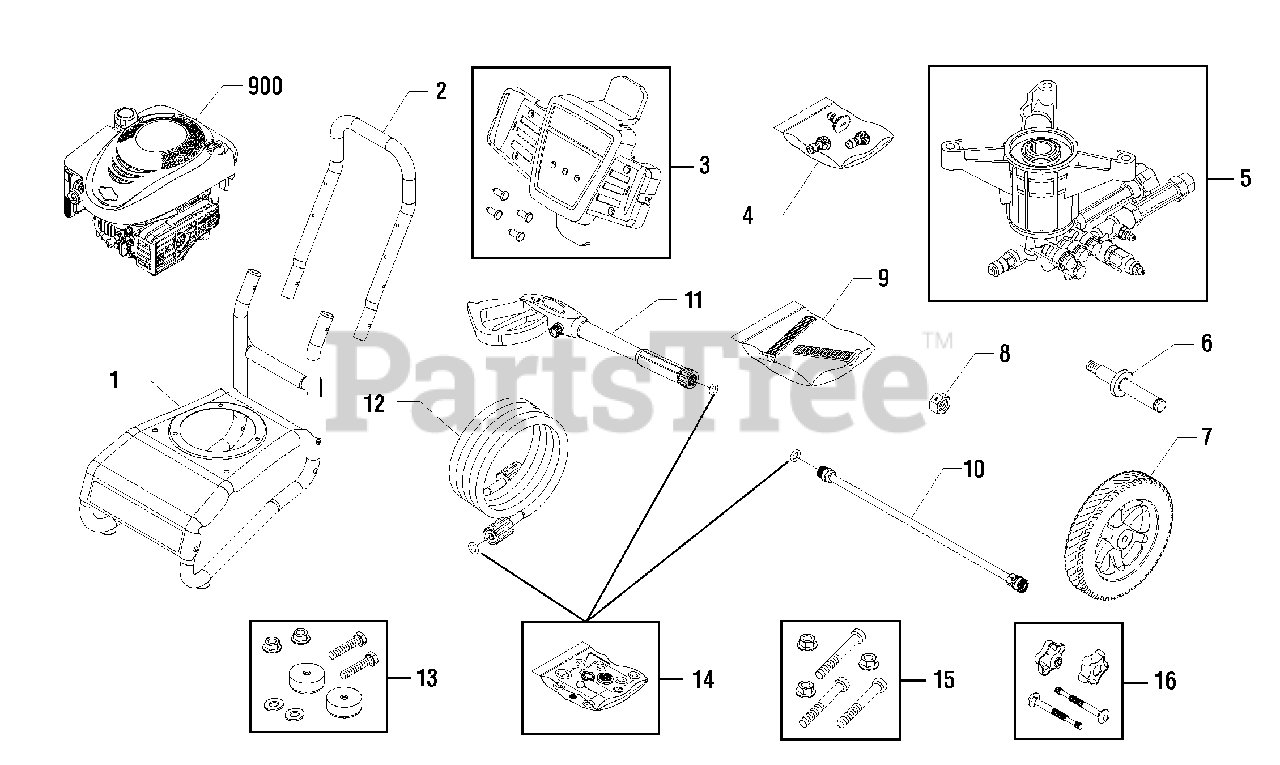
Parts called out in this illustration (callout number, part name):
1	BASE
10	EXTENSION, QC
11	GUN
12	HOSE
13	MOUNT, Vibration
14	KIT, 0-RING
15	KIT, Hardware, Pump Mounting
